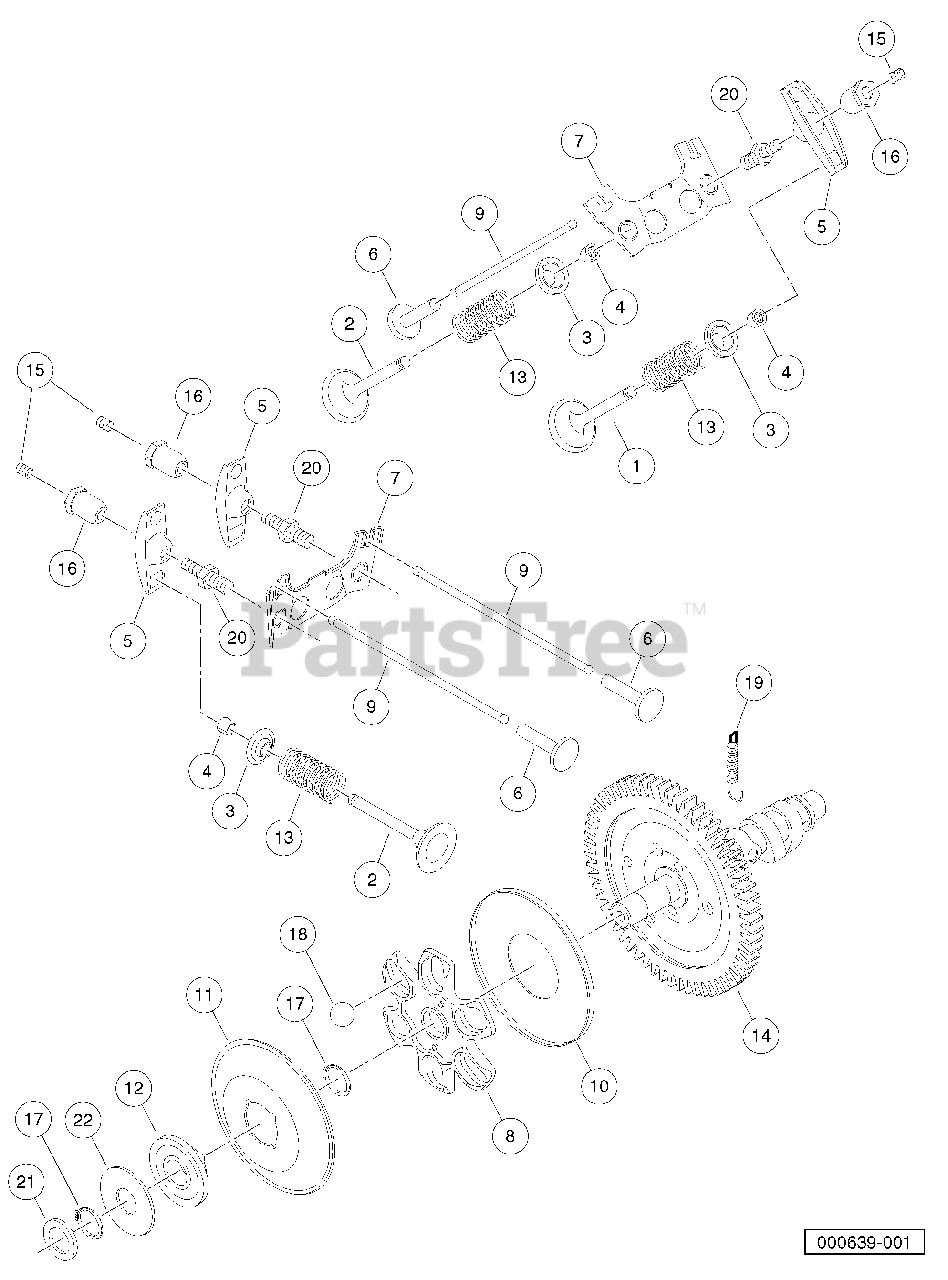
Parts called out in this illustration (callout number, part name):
1	Valve, Intake, Fh
2	Valve, Exhaust, Fh
3	Retainer, Valve Spring, Fh
4	Collet, Spring, Valve, Fh
5	Arm, Rocker
6	Tappet, Rod, Push, Fh
7	Guide, Arm, Rocker, Fh
8	Guide, Camshaft, Gov, Fh
9	Rod, Push, Fh
10	Plate, Camshaft, Gov, Fh
11	Plate, Ring, Gov, Fh
12	Sleeve, Plate, Gov, Fh
13	Spring, Valve, Fh
14	Kit, Camshaft, Comp, Fh
15	Screw, Rocker Arm, Fh
16	Nut, Arm, Rocker, Fh
17	Ring, Snap, Gov, Fh
18	Ball, Guide, Gov, Fh
19	Spring, Camshaft, Fh
20	Stud, Rocker Arm, Fh
21	Washer, Sleeve, Gov, Fh
22	Washer, Gov, Fh
